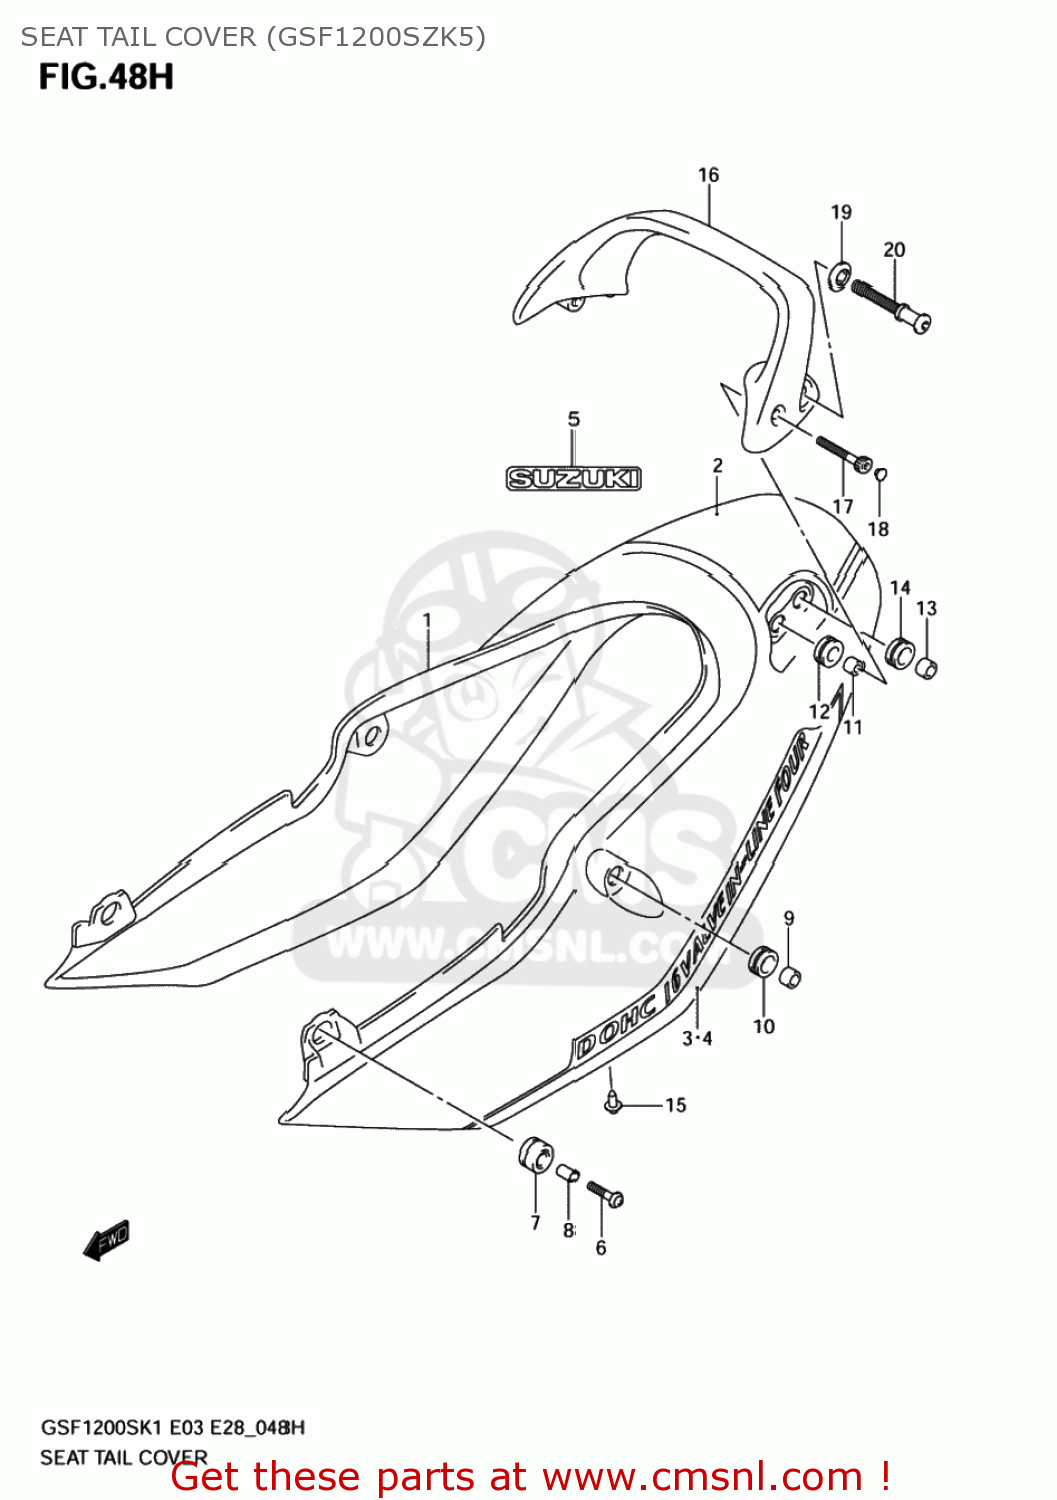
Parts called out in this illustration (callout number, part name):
1	COVER,SEAT TAIL
2	TAPE,SEAT TAIL COVER CTR
3	TAPE,SEAT TAIL COVER,R
4	TAPE,SEAT TAIL COVER,L
5	EMBLEM,SUZUKI
6	SCREW(6X30)
7	CUSHION,SEAT TAIL COVER FR
8	SPACER(6.5X10X13)
9	SPACER,8.5X14X9
10	CUSHION
11	SPACER(6.5X12X9)
12	CUSHION
13	SPACER,8.5X14X9
14	CUSHION
15	CLIP(BLACK)
16	HANDLE, PILLION RIDER (BLUE)
18	CAP(OD:10)
19	WASHER,HOOK
20	HOOK,PILLION RIDER HANDLE
